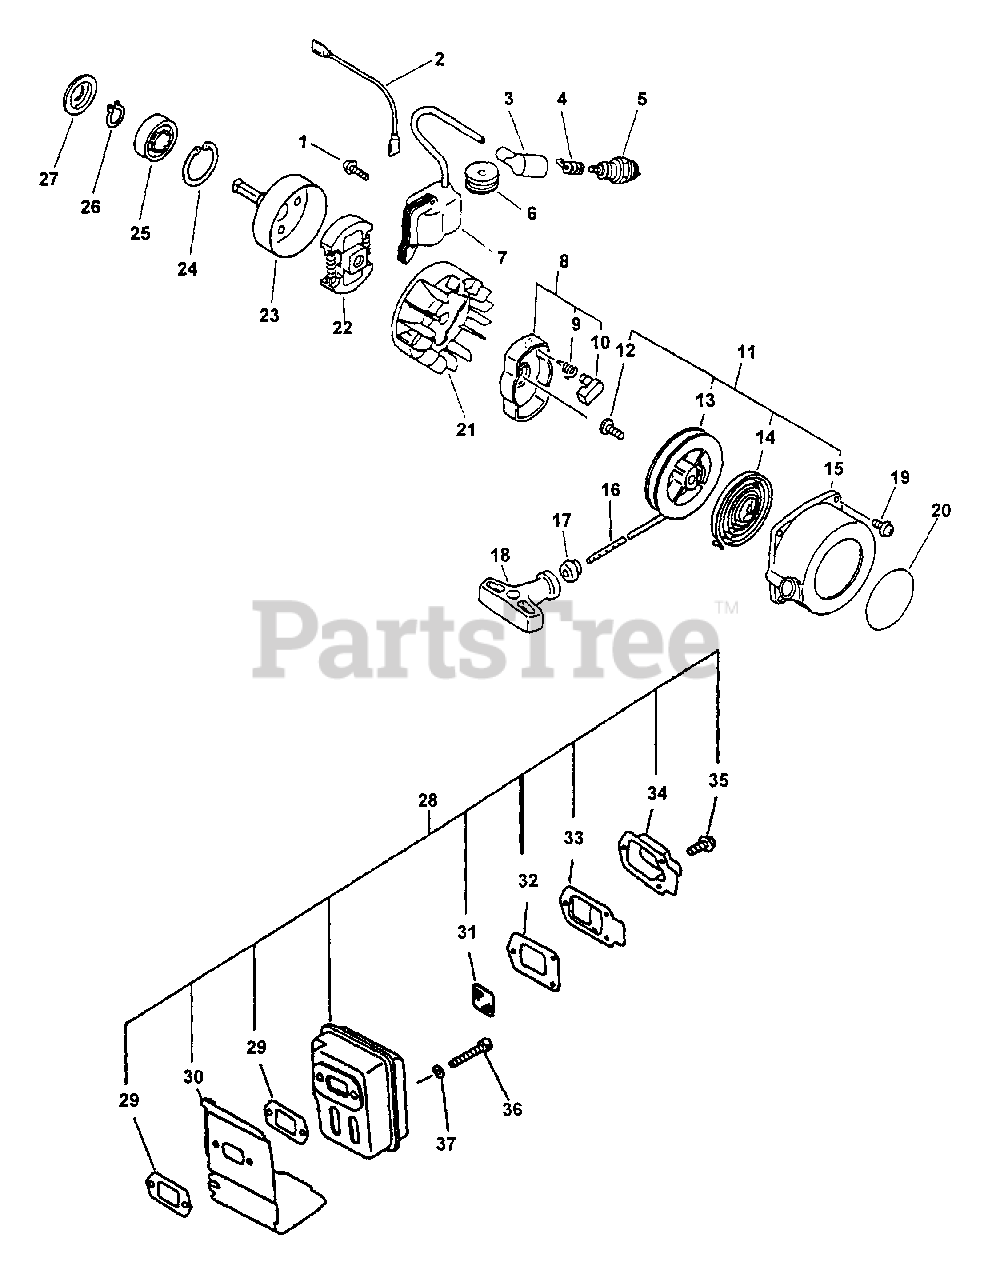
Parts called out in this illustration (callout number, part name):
1	SCREW 4×22
2	LEAD - GROUND
3	CAP, SPARK PLUG
4	TERMINAL, SPARK PLUG
5	SPARK PLUG - BPM-7Y
7	COIL, IGNITION
8	PAWL ASSY, STARTER
9	SPRING, RETURN
10	PAWL, STARTER - BLACK
11	STARTER ASSY, RECOIL
12	SCREW
13	REEL, ROPE
14	SPRING, RECOIL
15	CASE, RECOIL STARTER
17	GUIDE, ROPE
18	GRIP, STARTER
19	BOLT 4×16
20	LABEL, BRAND
22	CLUTCH ASSY
23	DRUM, CLUTCH
24	RING, SNAP Ø32
25	BEARING, BALL 6201-ZZ
26	RING, RETAINING - 12
27	STOPPER, PIPE
28	MUFFLER ASSY
29	GASKET, EXHAUST
30	COVER, EXHAUST
31	SCREEN, SPARK ARRESTER
32	GASKET, EXHAUST
33	GUIDE, EXHAUST
34	GUIDE, EXHAUST
34	OUTLET, EXHAUST
35	SCREW 4×10
36	BOLT 5×55
37	WASHER, FLAT 5.5×10×0.8
